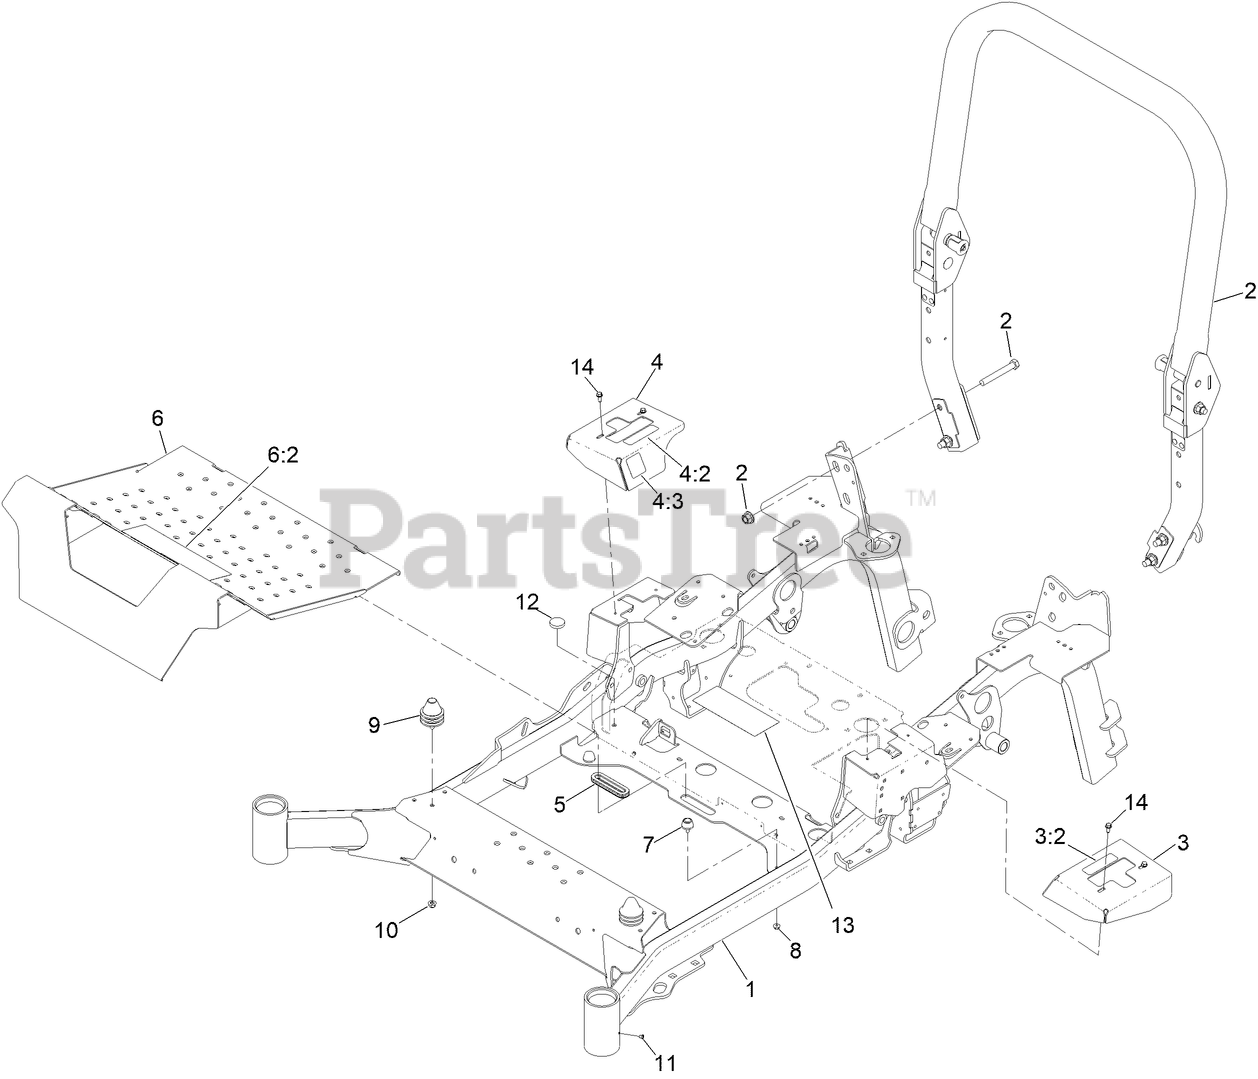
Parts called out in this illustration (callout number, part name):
1	MAINFRAME ASM, 60
2	ASM, ROPS-7500D DIESEL
3	COVER-MOTION CONTROL, LH
3:2	DECAL-CONTROL, MOTION
4	COVER-MOTION CONTROL, RH
4:2	DECAL-CONTROL, MOTION
4:3	DECAL-PARK BRAKE, CE
5	GROMMET-RUBBER
6	PAN-FLOOR
6:2	DECAL-DANGER
7	BUMPER-RUBBER
8	NUT-HF
9	ISOLATOR
10	NUT-HF, NI
12	BUMPER-PUSH-IN, RUBBER
13	DECAL-SERVICE AID
14	SCREW-HWH
